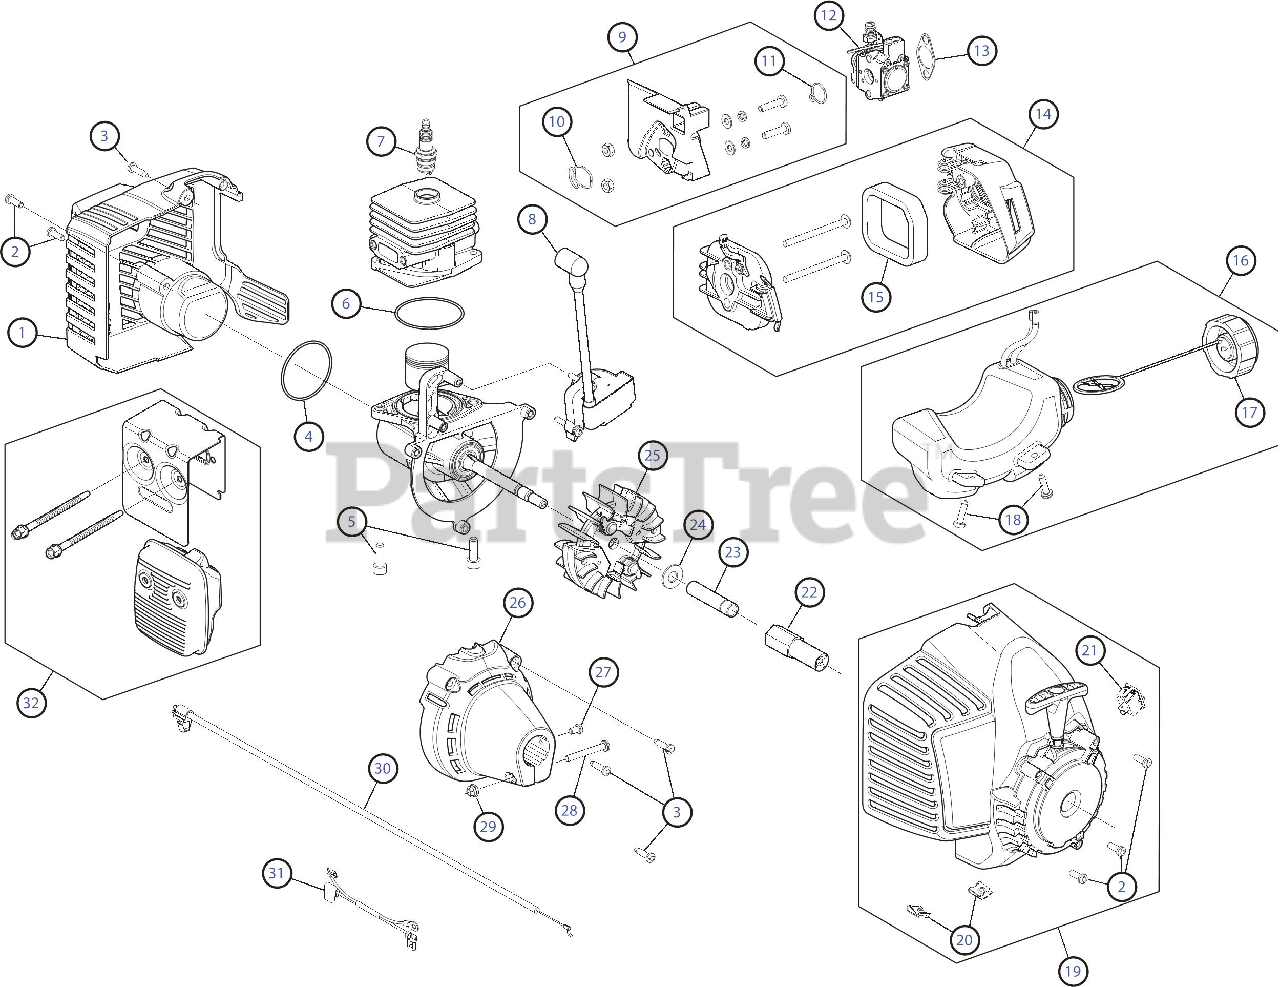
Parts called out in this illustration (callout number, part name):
1	Rear Cover Assembly
2	Housing Screw
3	Cover Screw
4	O-Ring
5	Crankcase Bolt
6	Crankcase O-Ring
7	Spark Plug
8	Module Assembly
9	Insulator Assembly
10	Insulator O-Ring
11	Carburetor O-Ring
12	Carburetor
13	Air Cleaner Gasket
14	Air Cleaner Cover Assembly
15	Air Cleaner Filter
16	Fuel Tank Assembly
17	Fuel Tank Cap
18	Fuel Tank Screw
19	Starter Housing
20	U-shaped Nut
21	Switch Assembly
22	Shaft Adapter
23	Spacer
24	Washer
25	Flywheel Assembly
26	Clutch Cover
27	Anti-rotation Screw
28	Clamp Screw
29	Clamp Nut
30	Throttle Cable
31	Lead Wires
32	Muffler Assembly
